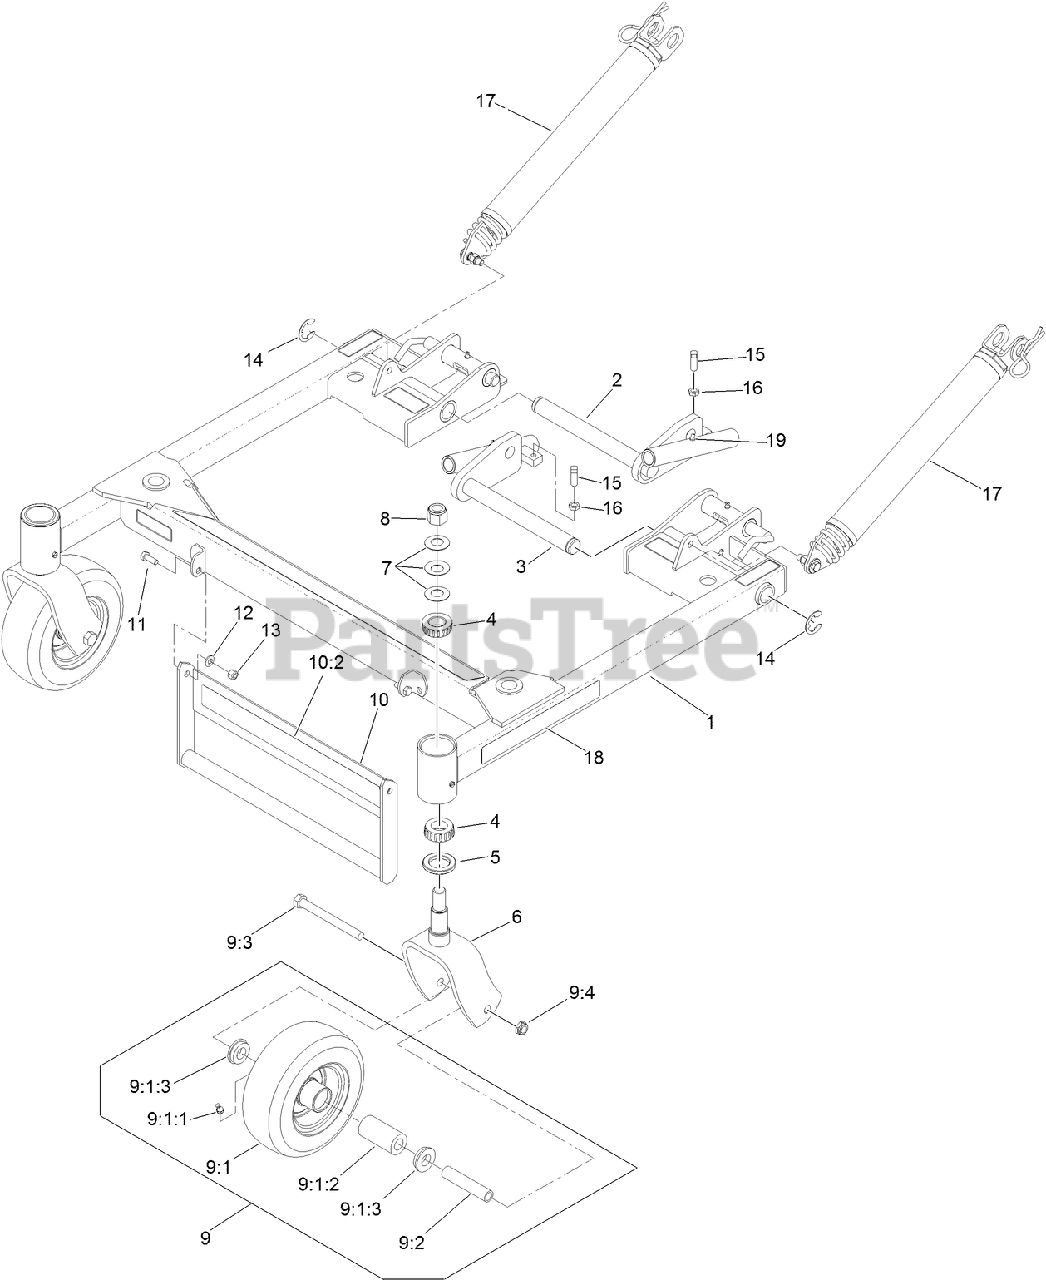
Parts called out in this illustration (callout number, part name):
1	DECK SUPPORT ASM
2	PIVOT-DECK, RH
3	PIVOT-DECK, LH
4	BEARING-ROLLER, TAPERED
5	SEAL-GREASE
6	FORK-CASTER
7	WASHER-BELLVILLE
8	NUT-LOCK, NI
9	WHEEL AND AXLE ASM
9:1	WHEEL AND TIRE
9:1:1	FITTING-GREASE
9:1:2	BEARING-ROLLER, STRAIGHT
9:1:3	BUSHING
9:2	SPACER-CASTER, FRONT
9:3	SCREW-HH
9:4	NUT-HEX
10	DECK LIFT HANDLE ASM
11	SCREW-HH
12	WASHER-SPRING
13	NUT-LOCK, NI
14	RING-SNAP
15	SCREW-SET, SQH
16	NUT-JAM
17	LIFT ASSIST SPRING ASM
19	FITTING-GREASE
